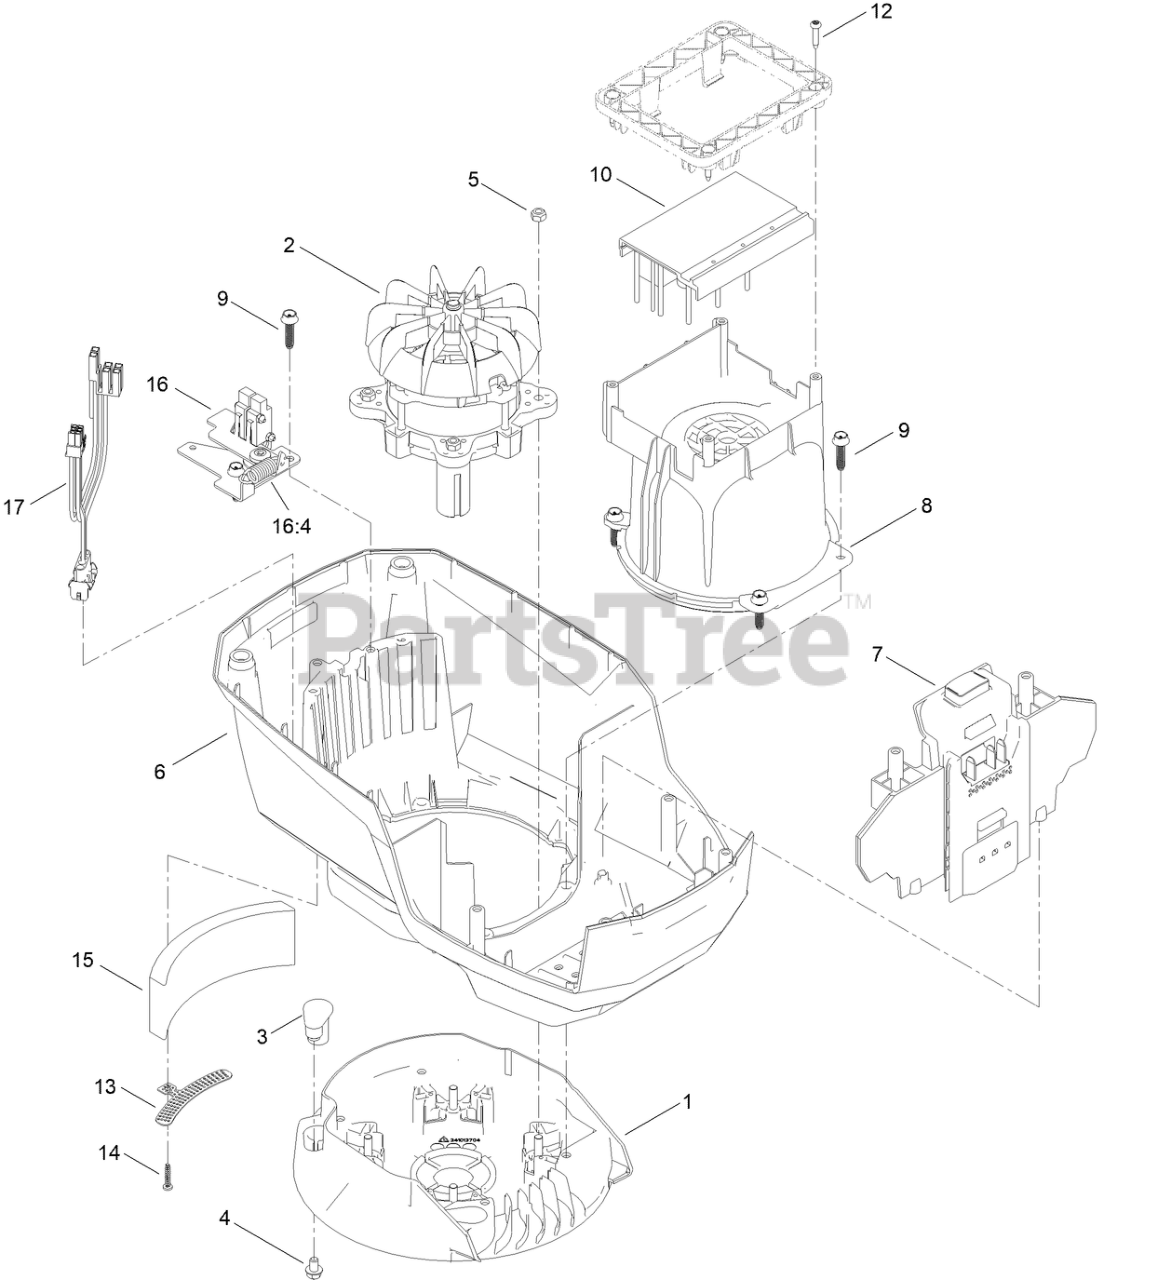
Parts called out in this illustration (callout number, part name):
1	BASE-MOUNT, MOTOR
2	MOTOR, 60 VOLT
3	INSERT-MOUNT, Motor
5	NUT-LOCK
6	SHROUD-LOWER
7	BATTERY RECIEVER ASM
8	SHROUD-MOTOR
9	SCREW-FLANGE, PLASTIC
10	CONTROLLER-MOTOR, 60V [2-SP]
13	BRACKET-FOAM
14	SCREW-PLASTIC, PPH
16	BAIL SWITCH ASM
16:4	SPRING-EXTENSION
17	HARNESS-WIRE
